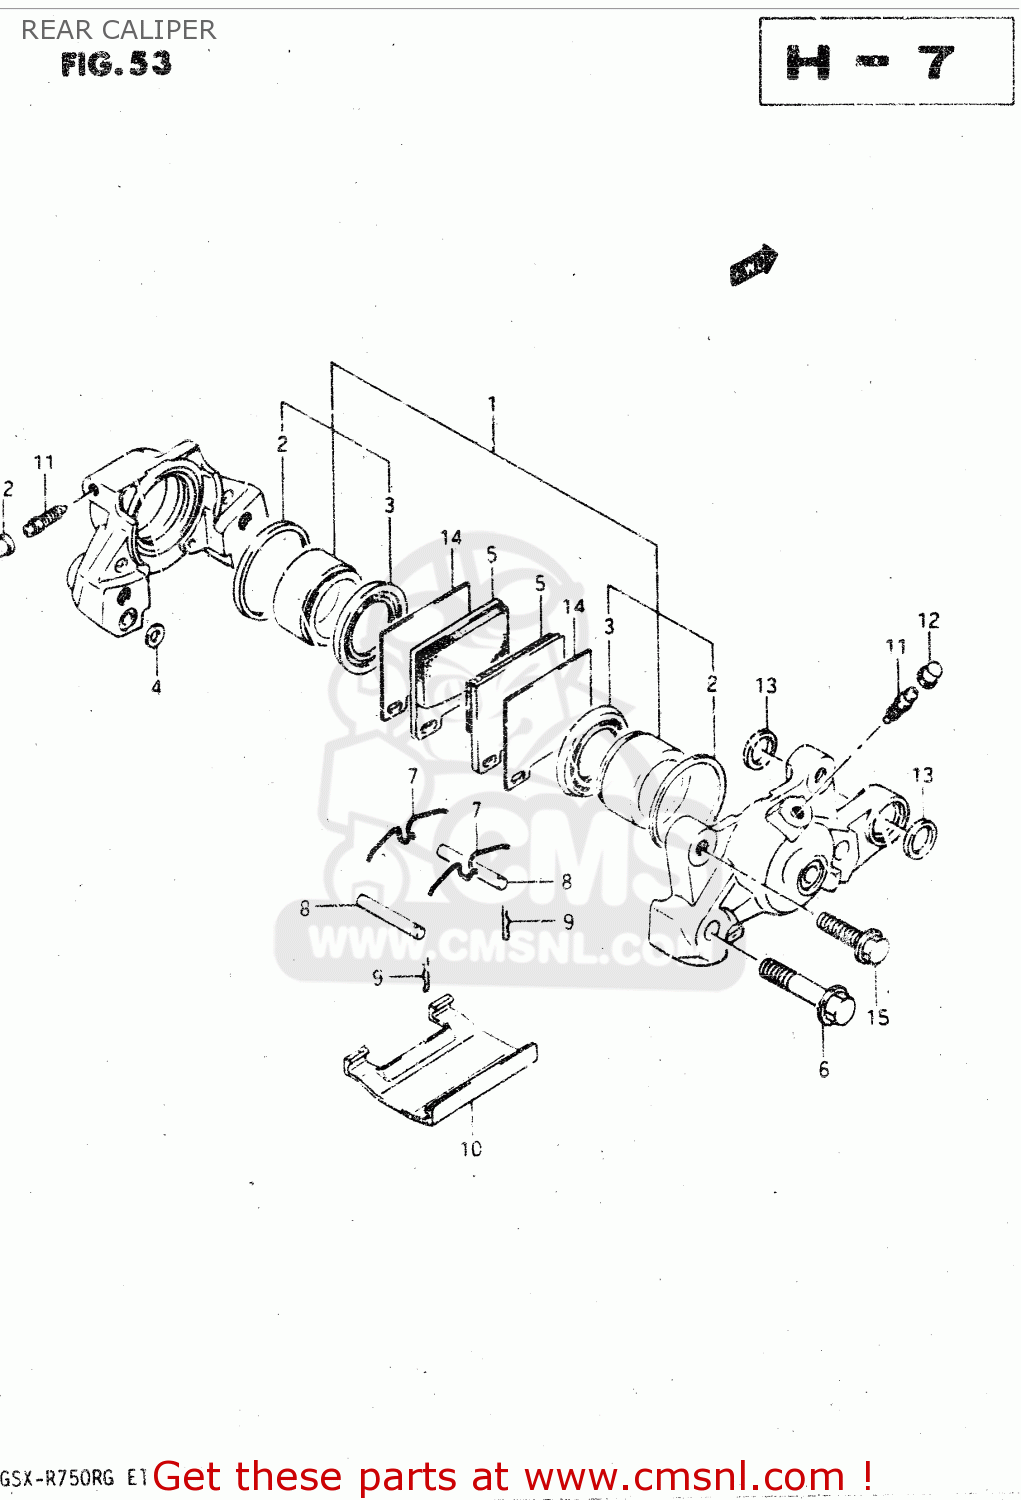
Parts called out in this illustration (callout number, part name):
1	PISTON SET
2	SEAL,PISTON
3	BOOT
4	SEAL
5	PAD,BRAKE
6	BOLT,HOUSING
7	SPRING
8	PIN,PAD
9	CLIP,PAD PIN
10	COVER,CALIPER
11	BLEEDER
12	CAP,BREATHER
13	SEAL,RR CUSHION ROD LWR
14	SHIM,PAD
15	BOLT
